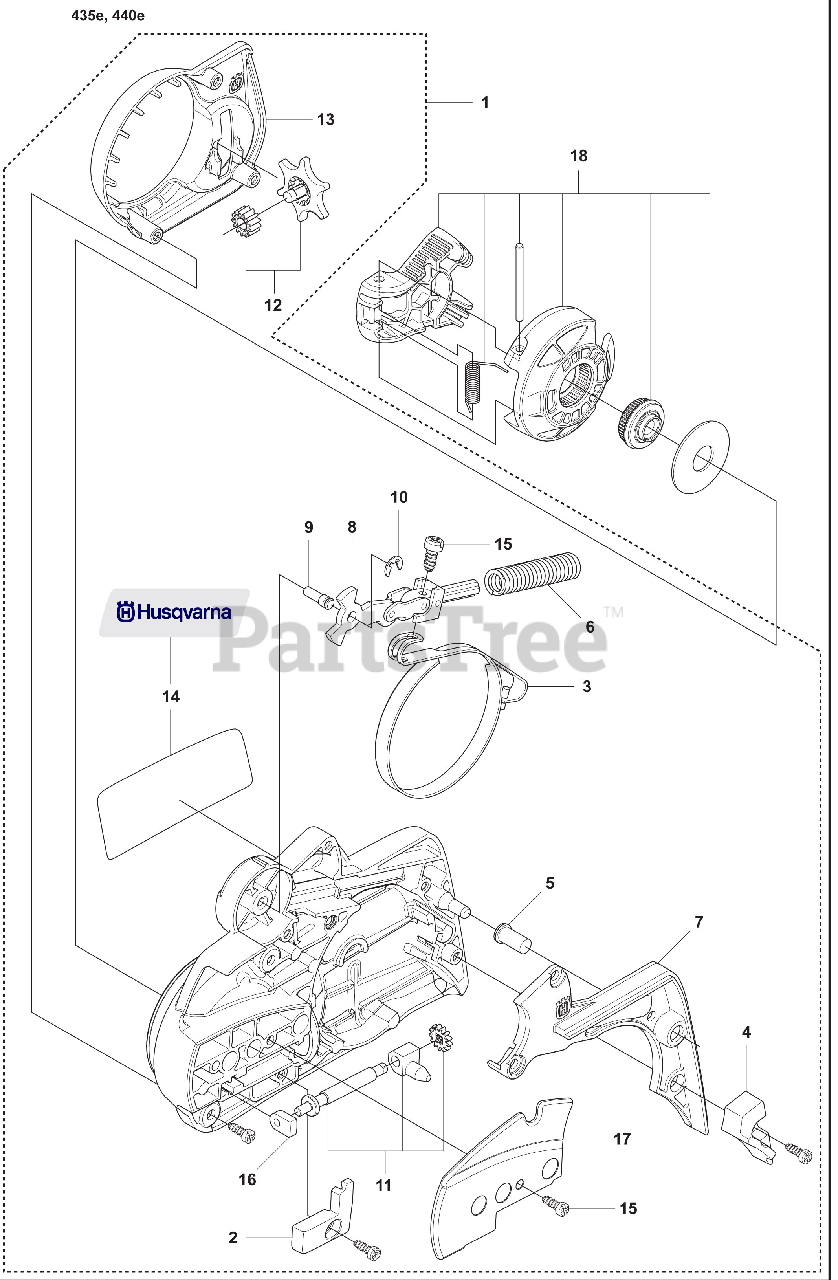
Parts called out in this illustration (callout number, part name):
1	CLUTCH COVER ASSY
2	COVER - USE 504 54 28-01
3	BRAKE BAND ASSY
4	WEAR PROTECTION
5	SLEEVE
6	RP BLADE GUARD
7	COVER
8	JOINT
9	PIN
10	E-RING 4
11	CHAIN TENSIONER SCREW, COMP.
12	CHAIN TENSIONER WHEEL, COMP.
13	HEAT SHIELD
14	DECAL, CLUTCH HOUSING
15	SCREW
16	RP BEARING SLEEVE
17	PLATE
18	KNOB, COMPLETE
